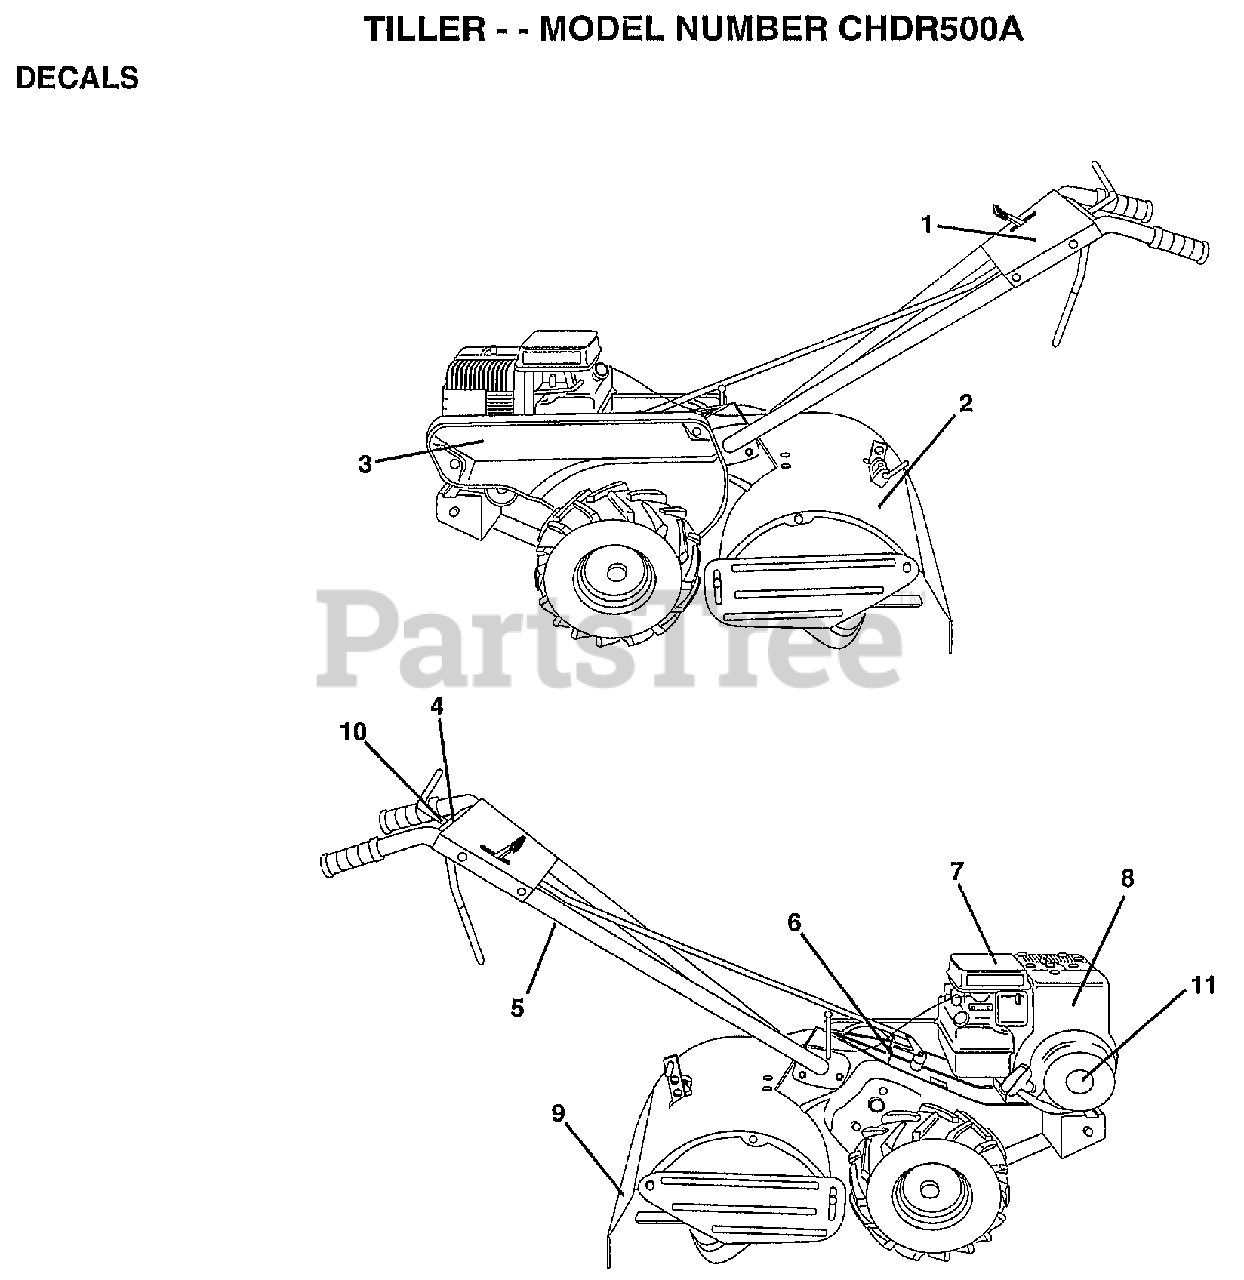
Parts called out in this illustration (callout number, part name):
1	"DECAL PANEL,CTRL"
2	"DECAL SHIELD,TINE"
3	"DECAL GUARD, BELT"
5	DECAL.HAND.PLACE
6	DECAL TI
7	DECAL TI
8	DECAL, BRIGGS & STRATTON
10	DECAL REVERSE
11	DECAL, 5 HP
